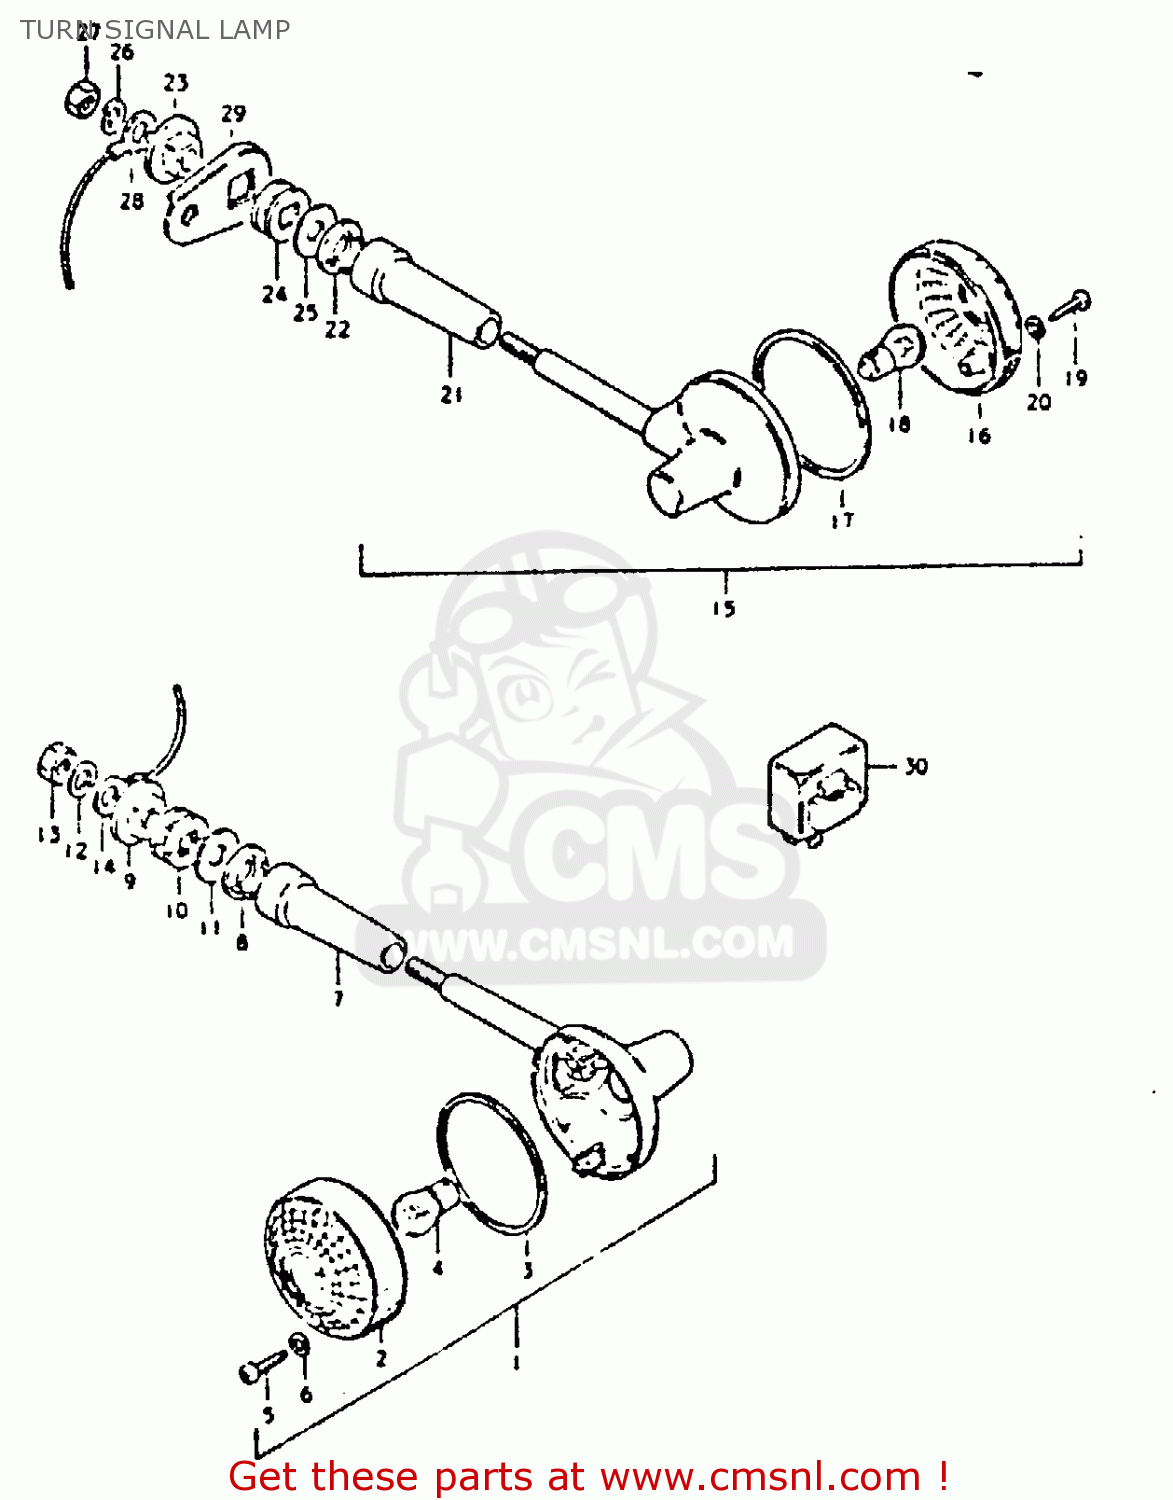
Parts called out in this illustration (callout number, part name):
1	LAMP, FRONT TURN SIGNAL
2	LENS
3	GASKET (NAS)
4	BULB 12V 21W
5	SCREW
6	GASKET (NAS)
7	COVER,STAY
8	SPACER
9	SPACER
10	CUSHION
11	WASHER (10.5X30X2.3)
12	LOCK WASHER
13	NUT
14	WIRE
15	LAMP, REAR TURN SIGNAL
16	LENS
17	GASKET (NAS)
18	BULB 12V 21W
19	SCREW
20	GASKET (NAS)
21	COVER,STAY
22	SPACER
23	SPACER
24	CUSHION
25	WASHER (10.5X30X2.3)
26	LOCK WASHER
27	NUT
28	WIRE
29	BRACKET,RR TURN SIGNAL LAMP
30	RELAY,TURN SIGNAL
